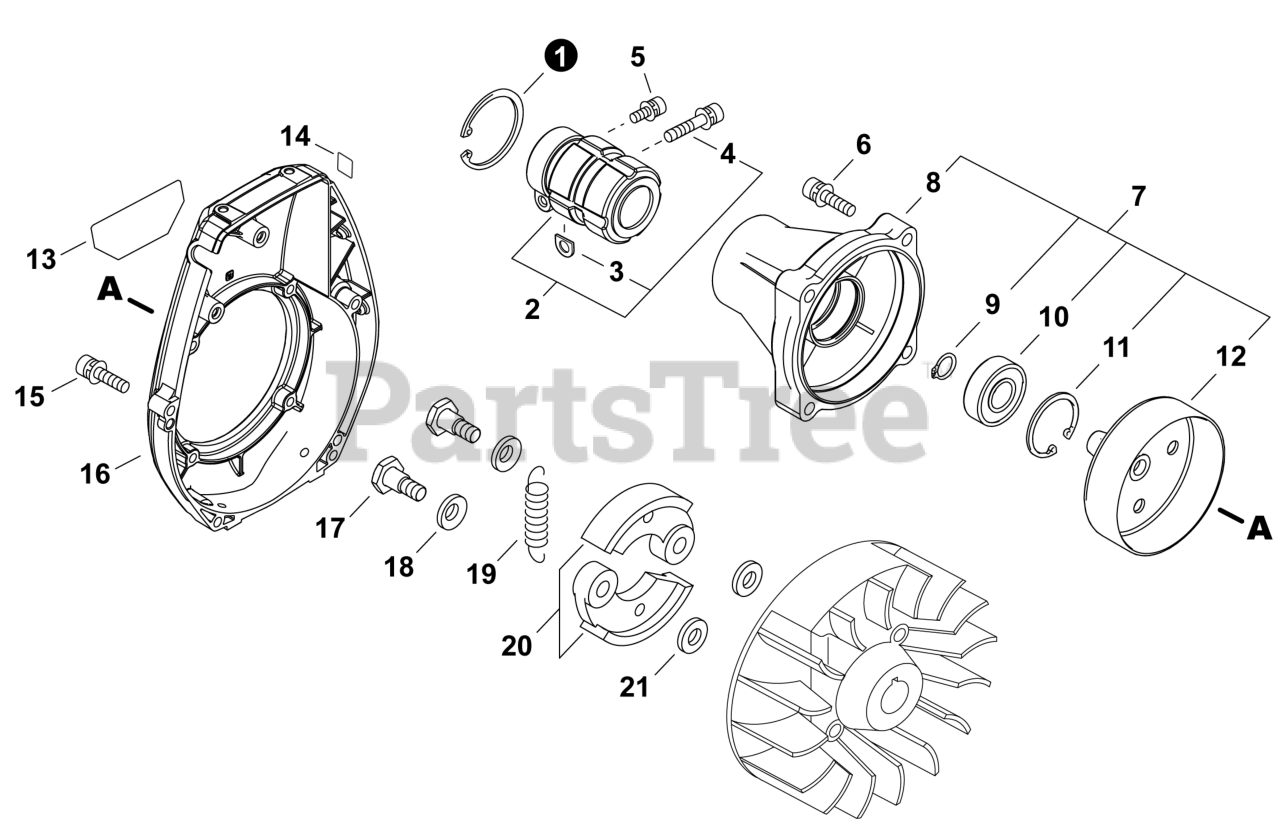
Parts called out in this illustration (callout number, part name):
1	RING, SNAP 45
2	CUSHION ASSY, MAIN PIPE
3	D-WASHER
4	BOLT 6x30
5	BOLT 5x12
6	BOLT 6x30
7	CASE ASSY, FAN
8	CASE, CLUTCH
9	RING, SNAP 15
10	BEARING, BALL
11	RING, SNAP 35
12	DRUM, CLUTCH
13	LABEL - MODEL B451
14	LABEL - CAUTION - HOT
15	BOLT 5x25
16	COVER, FAN
18	WASHER, WAVE
19	SPRING, CLUTCH
20	CLUTCH SHOE SET
21	WASHER 8.2x17x1.6
